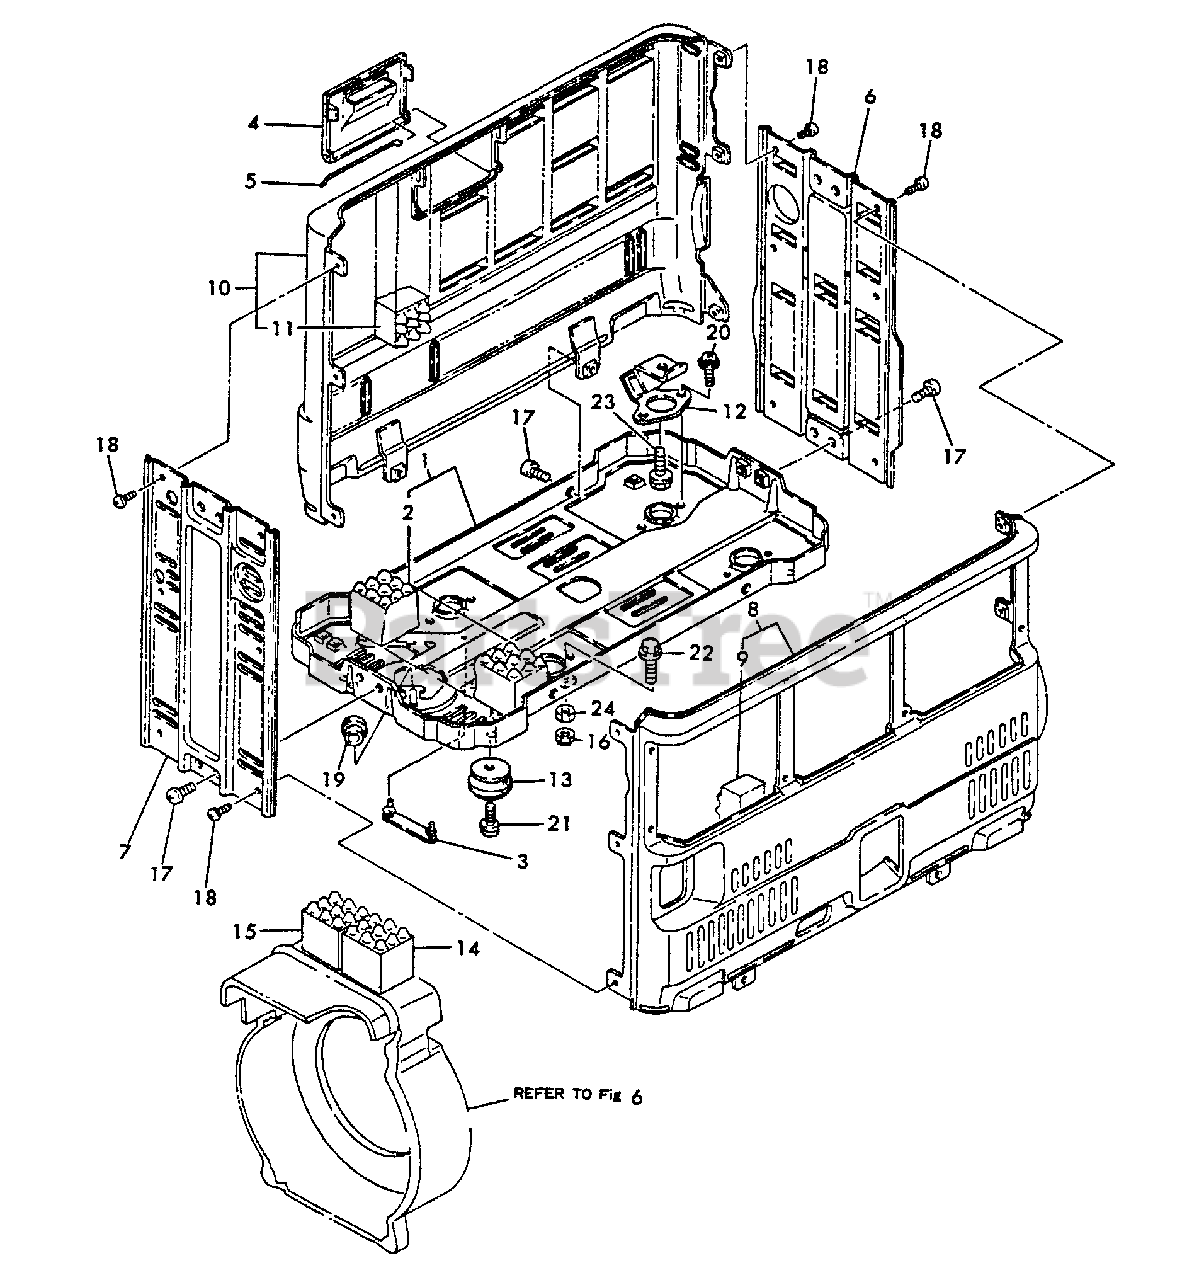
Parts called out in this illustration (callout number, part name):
1	CASE - BOTTOM
2	URETHANE FOAM (E)
3	HOLDER, TOOL
4	PLUG, BLIND
5	SPRING, HINGE
6	CASE - RIGHT
7	CASE - LEFT
8	CASE - FRONT
9	URETHANE FOAM (C)
10	GEAR CASE ASSY
11	URETHANE FOAM (D)
12	DAMPER (A)
13	DAMPER (B)
14	URETHANE FOAM (A)
15	URETHANE FOAM (B)
16	NUT
17	SCREW - 6X10
18	SCREW - 4X8
19	GROMMET
20	SCREW - 6X12
21	SCREW - 6X12
22	BOLT - 6X16 -- PLATED
23	BOLT - 8X14 -- PLATED
24	LOCKNUT - 6 -- PLATED
